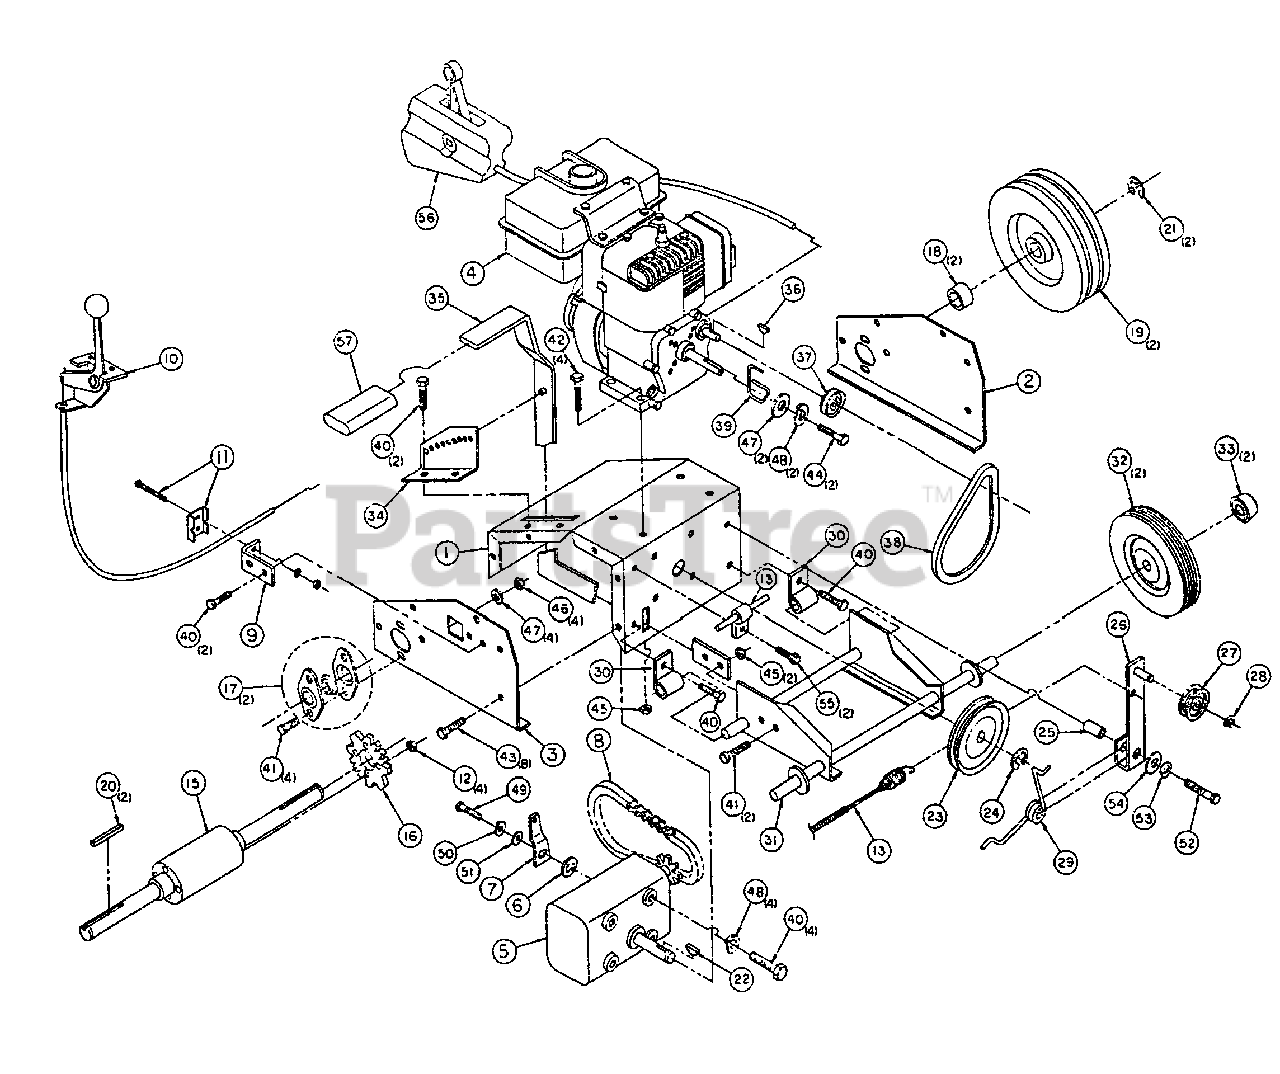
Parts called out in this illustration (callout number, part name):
1	Engine Base Weldment
2	Left Side Weldment
3	Right Side Weldment
4	Engine,
5	Transmission
6	Washer Shift Lever
7	Shift Lever
8	#40 Chain .5 Pitch x 24"
9	Shift Cable Bracket
10	Shift Cable
11	Clamp Assembly
12	Bottom Cover
13	Clutch Cable Assembly
15	Differential
16	Sprocket
17	2 Hole Flange Bearing
18	Wheel Spacer
19	Pneumatic Wheel
20	3/16" x 3/16" x 1-1/2" Shaft Key
21	3/4" Dia. E-Ring
22	#606 Woodruff Key
23	Transmission Pulley
24	5/8" Dia. E-Ring
26	Idler Arm
27	Idler Pulley
28	3/8" Dia. E-Ring
29	Idler Spring
30	Pivot Mount
31	Wheel Frame
33	Push Nut Cap
34	Height Adjuster Plate
35	Height Adjuster Handle
36	#405 Woodruff Key
37	Engine Pulley
39	Belt Guide
40	5/16-18 x 3/4" HHCS Pltd.
41	5/16-18 x 1, HHCS
42	5/16-28 x 1-1/4" Pltd.
43	5/16-18 x 3/4" Self-Tapping Cap Screw Pltd.
44	5/16-24 x 3/4" HHCS
45	5/16-18 Whiz Locknut Pltd.
46	5/16-18 Nylok Locknut Pltd.
47	5/16" Flatwasher Pltd.
48	5/16" Med. Split Lockwasher Pltd.
49	1/4-28 x 3/4" HHCS Pltd.
50	1/4" Med. Split Lockwasher Pltd.
51	1/4" Flatwasher Pltd.
52	3/8-16 x 1-3/4" HHCS Pltd.
53	3/8" Med. Split Lockwasher Pltd.
54	3/8" Flatwasher Pltd.
55	10-24 x 1/2" Self-Tapping Cap Screw
56	Throttle Cable
57	Grip-Height Adjuster
